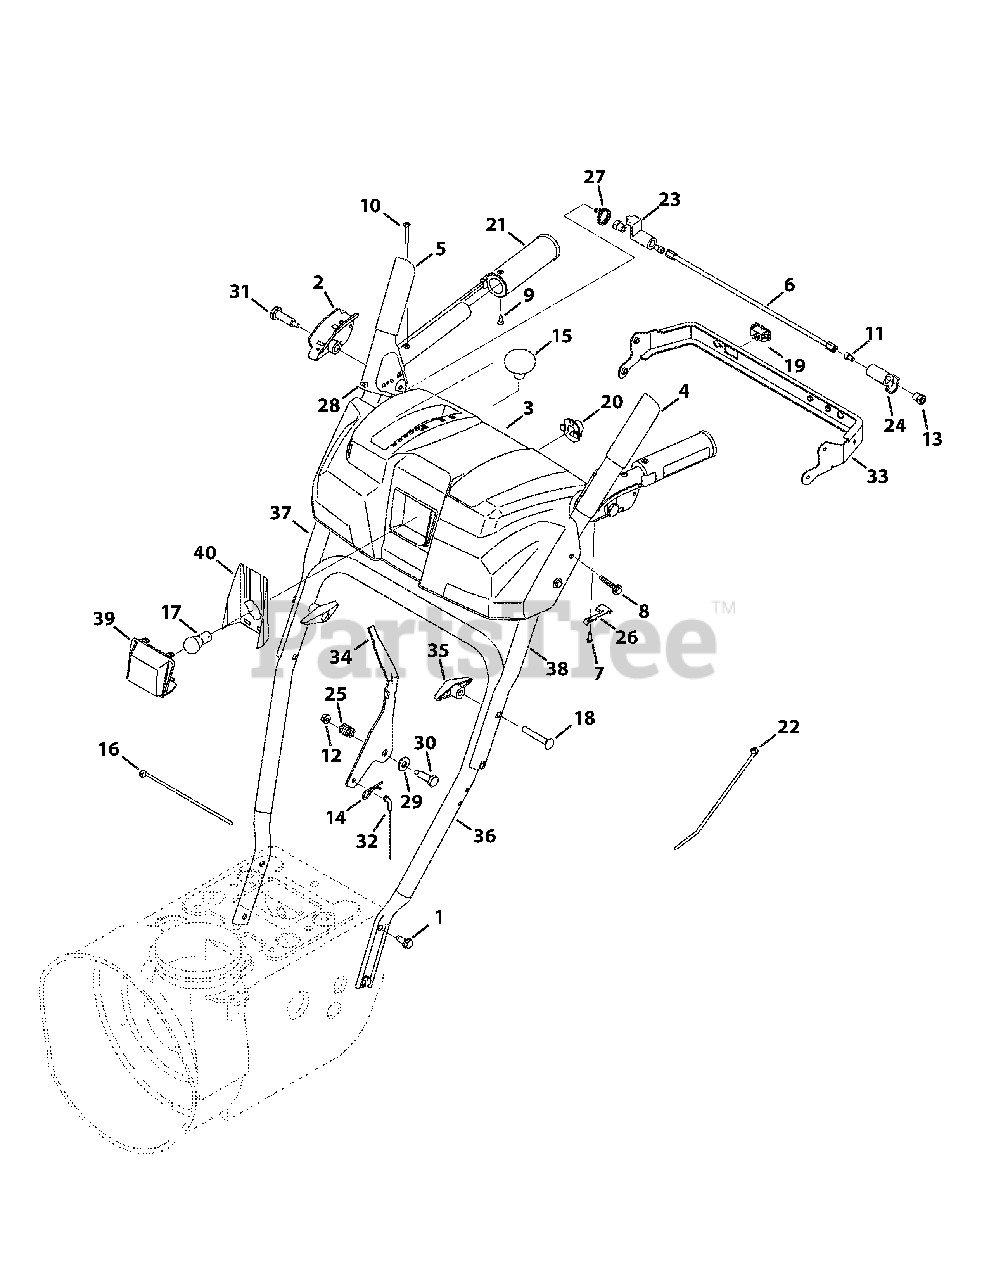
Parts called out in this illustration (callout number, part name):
1	Screw, Taptite, 5/16-18 x .750
2	Clutch Lock, RH
2	Clutch Lock, LH
3	Handle Panel w/ Light
3	Handle Panel w/o Light
4	Auger Engage
5	Drive Engage
7	Screw, Plastite, 8-16 x .50
8	Screw, Taptite, 1/4-20 x 1.625
9	Screw, 10-16 x 0.625
10	Screw, 10-24 x 1.375
11	Screw, 1/4-20 x .50
12	Nut, Flangelock, 1/4-20
13	Nut, Hex, 1/4-20
14	Click Pin, .092 x 1.64
15	Shift Knob
16	Cable Tie, 7"
17	Lamp, 12.8V - 26" & 28" Models
17	Lamp - 24" Models
18	Screw, Carriage, 5/16-48 x 2.25
19	Heated Grip Switch
20	Lamp Socket
21	Heated Grip - 26" & 28" Models
21	Grip - 24" Models
22	Cable Tie, Push Mount
23	Plate, Lock
24	Cam, Clutch Lock
25	Compression Spring, .39 x .60 x .88
26	Clutch Lock Spring
27	Torsion Spring, 0.8156 x .3038
28	Rubber Bumper
29	Washer, Flat, .385 x .87
30	Screw, Shield, .374 x 1.05
31	Screw, Shoulder, .437 x 1.345 x 1/4-20
32	Speed Selector Cable
33	Panel Bracket
34	Shift Lever
35	Wing Knob
36	Lower Handle
37	Upper RH Handle
38	Upper LH Handle
39	Lens Panel, Troy-Bilt
40	Lens Label, Troy-Bilt
